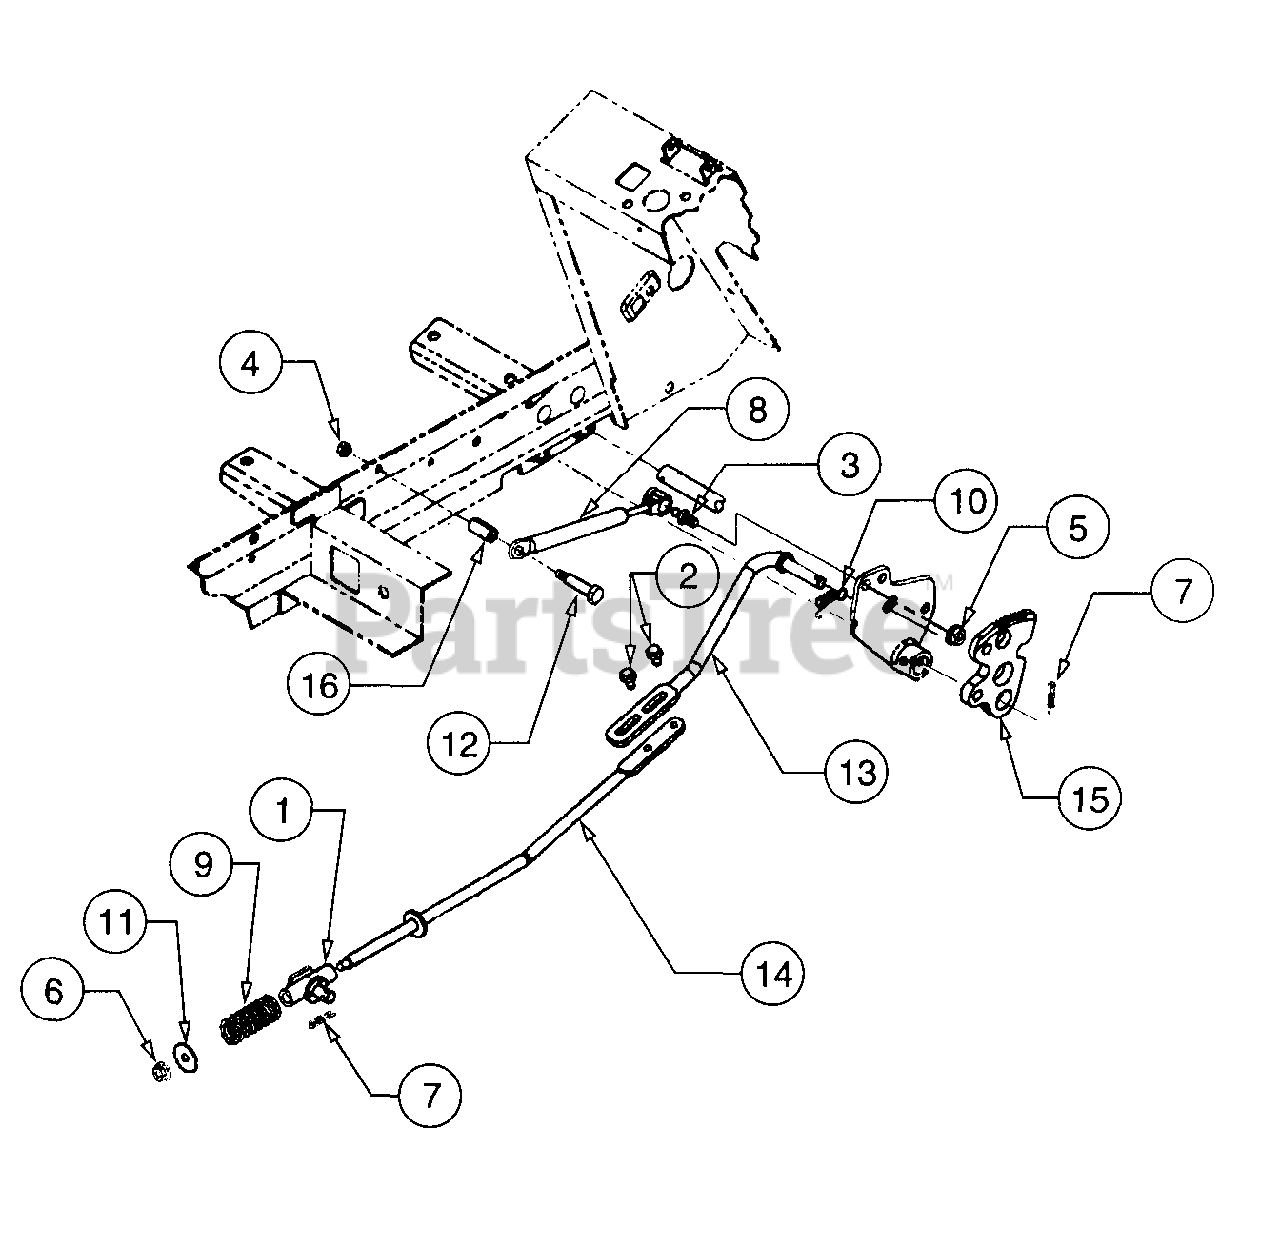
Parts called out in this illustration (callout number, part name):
1	Pivot Assembly
2	Screw, Hex Wash Hd Tapp 1/4-20 x .5
3	Screw, Ball, 5/16-18 x .56
4	Nut, Hex Sems, 1/4-20
5	Nut, Hex Flange Lock, 5/16-18 GR5
6	Nut, Hex Flange Lock, 1/4-20
7	Pin, Internal Cotter
8	Cylinder, Damper
9	Spring, Compression, .63 ID x 2.0 Lg
10	Spring, Extension, 3/8 OD x 1.44
11	Washer, Flat, .265 x 1.0 x .030
12	Bolt, Shoulder, .374 Dia x 1.375
13	Rod, Front Control
14	Rod, Rear Hydro Control
15	Plate, Cruise
16	Spacer, Split Tubing, .375 ID x 1.04
